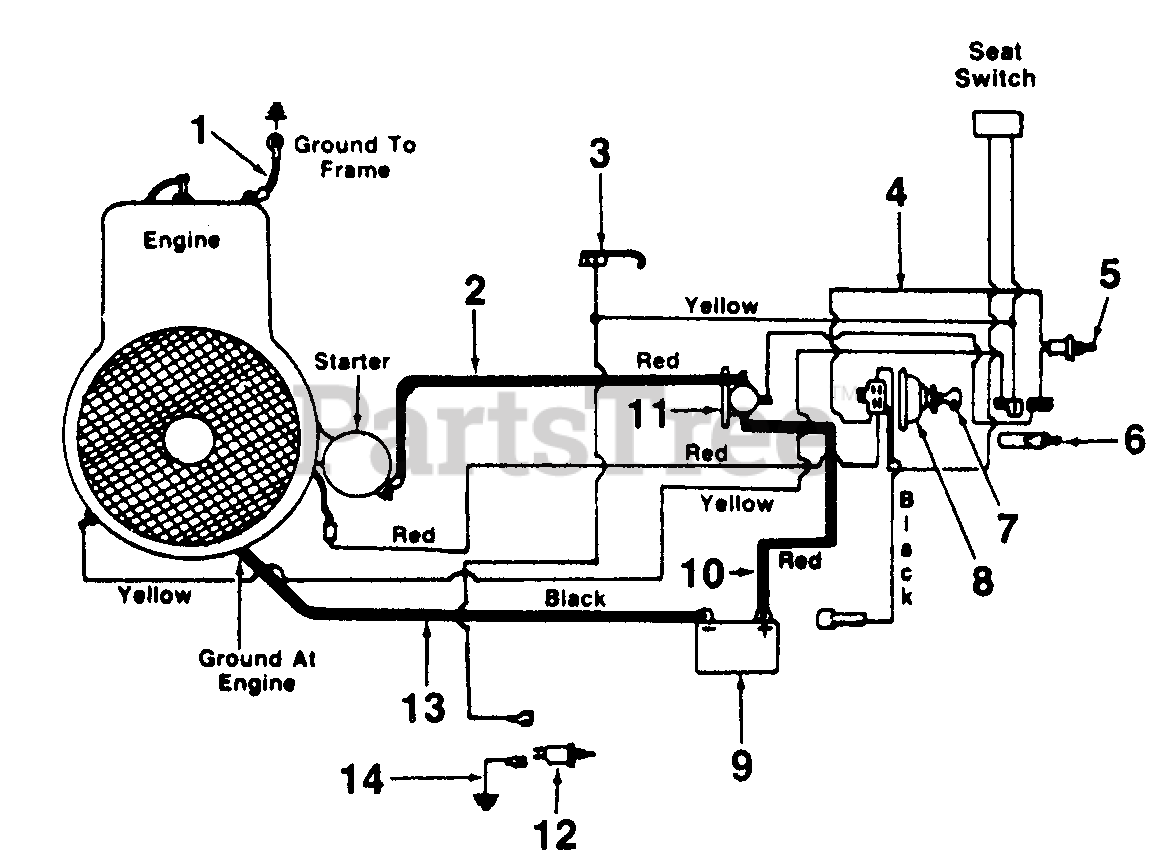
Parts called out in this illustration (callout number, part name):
1	Elec. Wire 8 Ga. x 9.0" Lg.
2	Elec. Wire
3	Spring Switch-Reverse
4	Wire Harness
5	Safety Switch-Black N.O.
6	Safety Switch
7	Ignition Key
8	Ignition Switch
9	Battery 12V
10	Elec. Wire Red w/Boot
11	Solenoid
12	Safety Switch Red N.C.
13	Elec. Wire 8 Ga. x 9.0" Lg.
14	Elec. Wire
